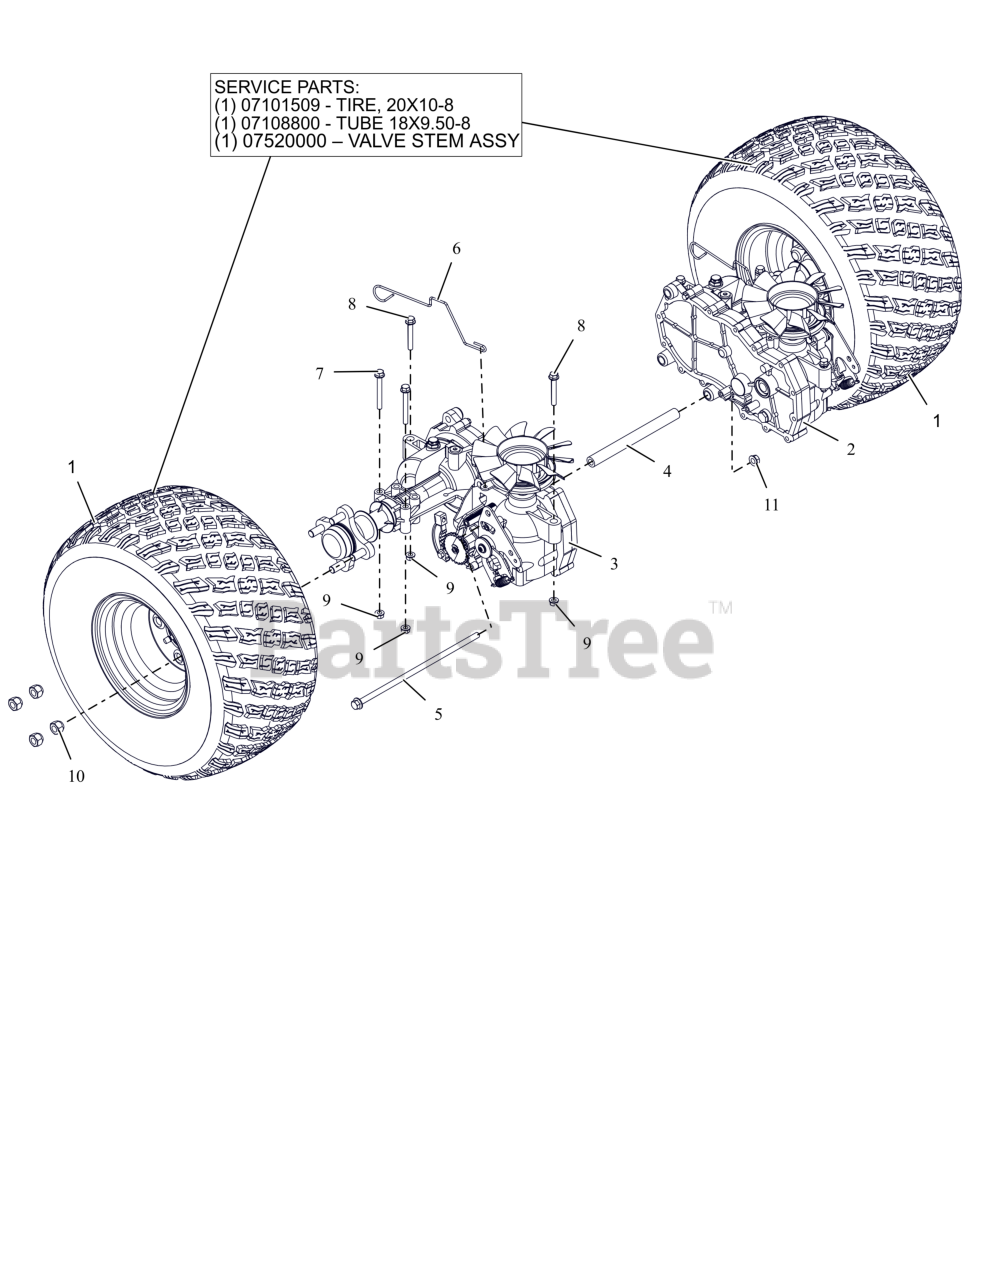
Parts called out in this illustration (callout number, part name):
1	ASM- TIRE/WHL 20X10-8
1	TIRE- 20X10-8
1	TUBE 18X6.50/8.50/9.50-8/20X8.00/10.00-8
1	VALVE STEM ASS'Y
2	TRANSAXLE- SERVICEABLE EZT -LH
3	TRANSAXLE- SERVICEABLE EZT -RH
4	SPCR, TRANSAXLE .438 ID X .750 OD X 8.18 (BLACK)
5	BLT, HEX-FLG 0.375-16X11.5 GR5 ZC120
6	WIRE- DUMP VALVE LEVER
7	BLT,HEX-FLG .31-18X2.75 G5 ZCC
8	BLT,HEX-FLG .31-18X2.25 G5 ZCC
9	NUT,LK-CTR-FLG .31-18 GF ZCC
10	NUT, WHEEL .50-20 ZCC
11	NUT-LK-CTR-FLG .375-16 GF ZCC
